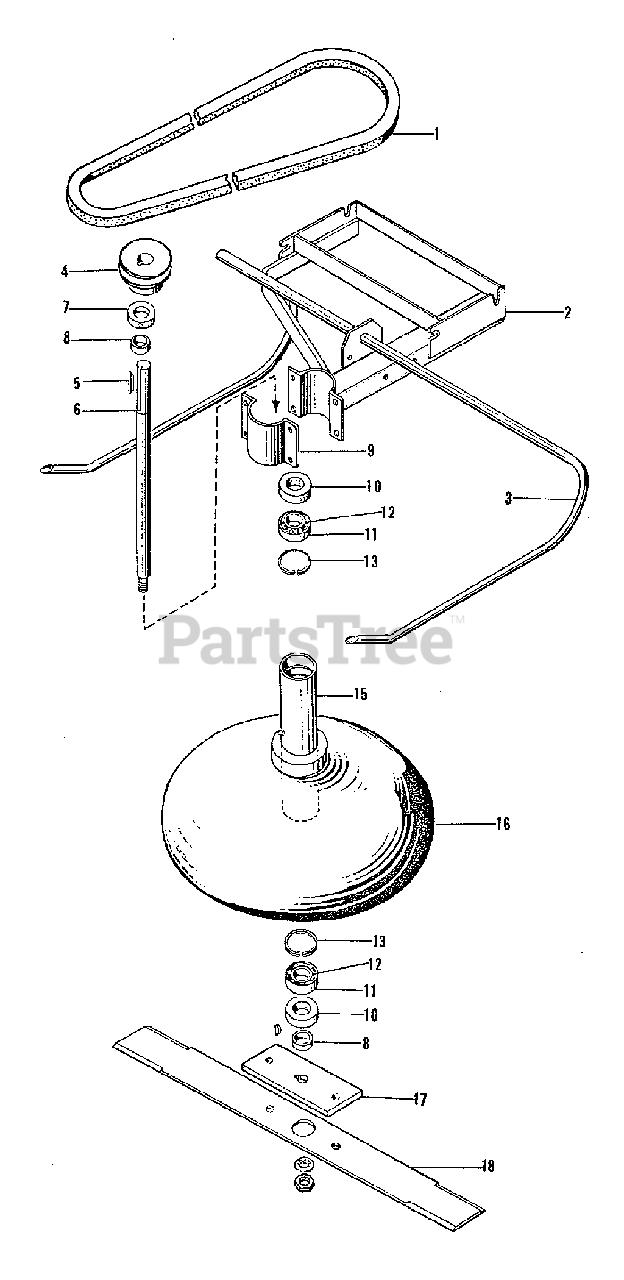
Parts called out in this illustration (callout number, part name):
1	BELT, Drive, 49"
2	PUSH ARM ASSEMBLY
3	GAGE SHOE ASSSEMBLY
4	PULLEY, Arbor
5	KEY, Arbor Pulley
7	COLLAR, Set
8	SPACER, Arbor
9	CLAMP, Bearing Housing
10	SEAL, Oil
11	ROLLER BEARING, Cup
12	ROLLER BEARING, Cone
13	RING, Retaining
15	BEARING HOUSING, Arbor
16	DEFLECTOR ASSEMBLY
17	FLANGE, Arbor
18	BLADE, Knife
